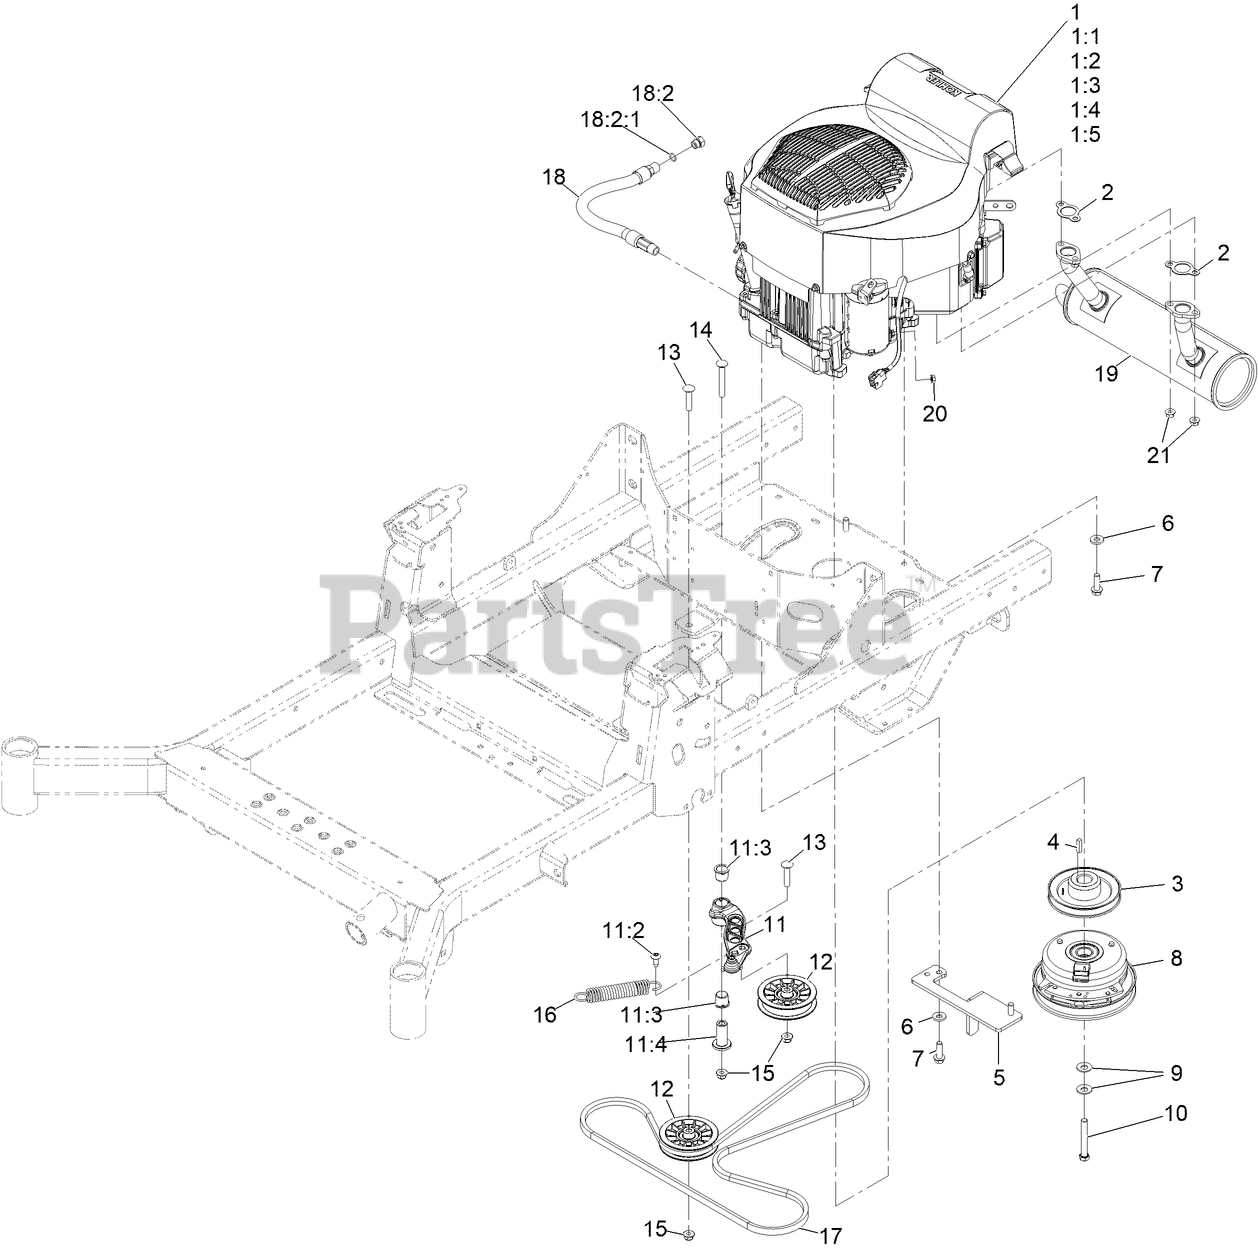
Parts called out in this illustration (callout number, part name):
1:1	ELEMENT-PRE CLEANER
1:2	ELEMENT-AIR FILTER
1:3	Filter-Oil
1:4	Filter-Fuel
1:5	Plug-Spark
2	GASKET (KOHLER)
3	SHEAVE, ENGINE
5	Anchor-Clutch
6	WASHER-BELLEVILLE
7	SCREW-THD
8	CLUTCH - 1.00 HD
9	WASHER-SPRING
10	SCREW-HH W/LOCTITE
11	ASM, PUMP IDLER
11:2	SCREW, TAPTITE
11:3	BUSHING, IGUS
11:4	Spacer, Idler Pivot
12	PULLEY-FLAT IDLER
13	SCREW-CARR
14	SCREW-CARR
15	NUT-HF, NI
16	SPRING-EXTENSION
17	BELT-V
18	OIL DRAIN HOSE ASM
18:2	PLUG-HH
18:2:1	O-RING
19	MUFFLER, KOHLER
21	NUT-FLANGE
